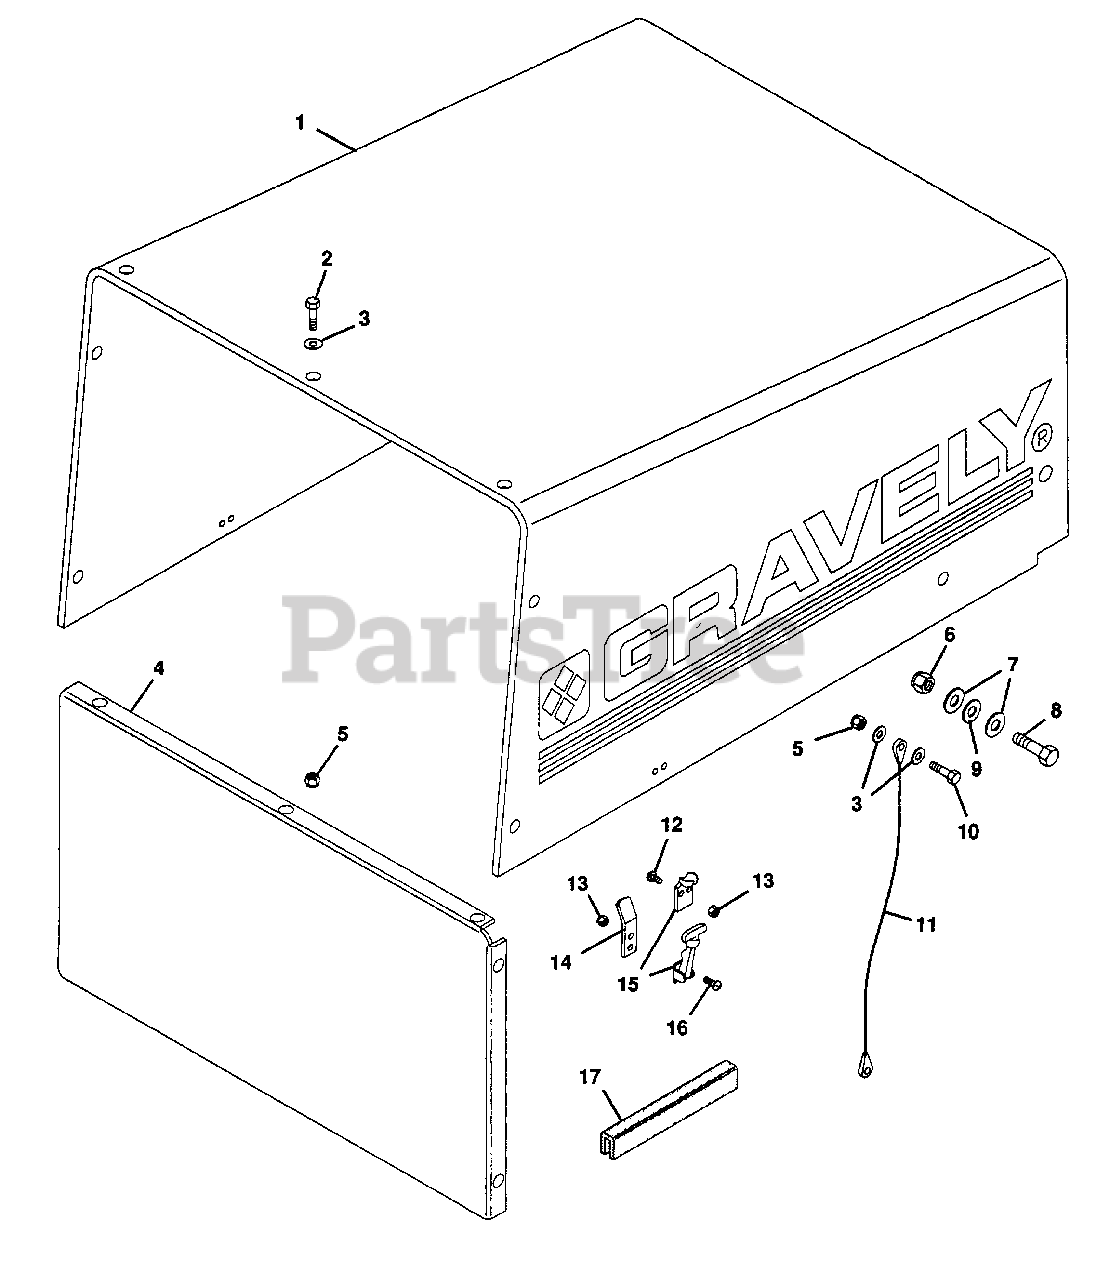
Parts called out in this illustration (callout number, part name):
1	Hood, Silk Screen
2	Bolt, Hex 1/4-20x.625
3	Washer, Flat .281x.625x.065
4	Baffle, Hood
5	Nut, Lock 1/4-20
6	Nut, Lock 3/8-16
7	Washer, Flat .406x.812x.065
8	Bolt, Hex 3/8-16x.875
9	Washer, Nylon .375x.75x.060
10	Bolt, Hex 1/4-20x.875
11	Cable, Hood
12	Screw, Machine 10-24x.50 PHD
13	Nut, Lock 10-24
14	Plate, Guide
15	Latch
16	Screw, Machine 10-24x.75 PHD
17	Strip, Cowl
